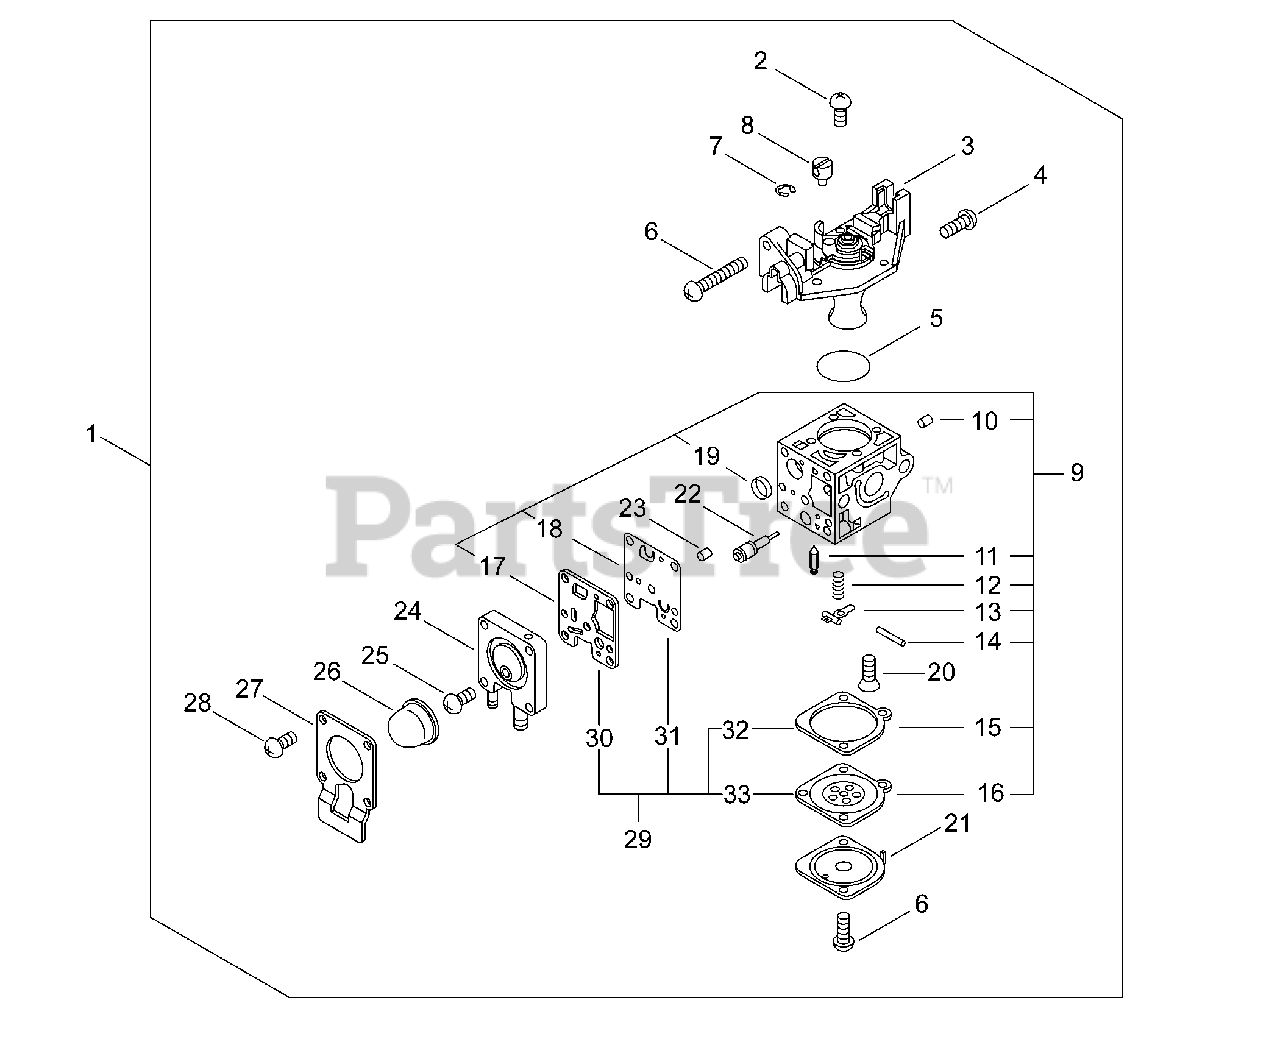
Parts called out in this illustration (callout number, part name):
1	CARBURETOR RB-K119
3	COVER ASSY, ROTOR
6	SCREW, IDLE ADJUST
9	GASKET / DIAPHRAGM KIT
10	GUIDE, ROLLER
11	VALVE, INLET NEEDLE
12	SPRING, METERING LEVER
13	LEVER, METERING
14	PIN, METERING LEVER
15	GASKET, METERING
16	DIAPHRAGM, METERING
17	GASKET, PUMP
18	DIAPHRAGM, PUMP
19	STRAINER
21	COVER, METERING DIAPHRAGM
22	NEEDLE, HIGH SPEED
24	BODY ASSY, PURGE
26	BULB, PURGE
27	RETAINER, PURGE BULB
29	REPAIR KIT, CARBURETOR
30	GASKET, PUMP
31	DIAPHRAGM, PUMP
32	GASKET, METERING
33	DIAPHRAGM, METERING
